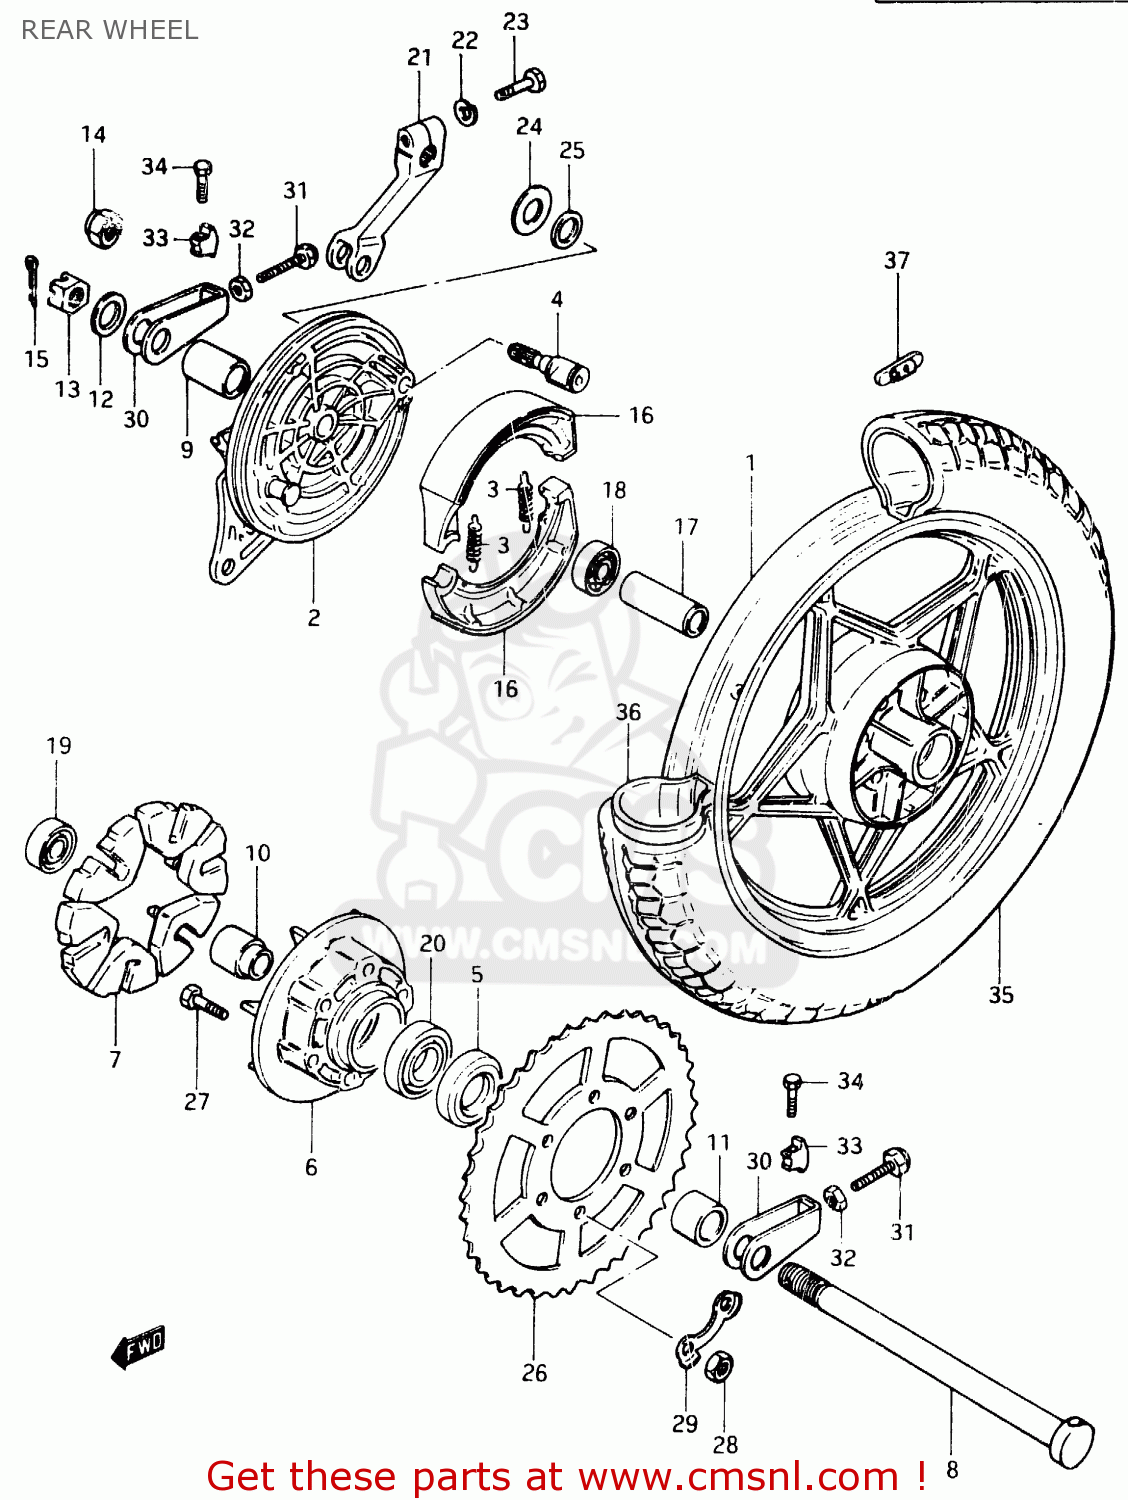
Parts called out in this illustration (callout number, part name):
1	CASTING WHEEL,REAR 1.85-
2	PANEL,REAR HUB
3	SPRING,BRAKE SHOE
4	CAM,FRONT BRAKE
5	SEAL,OIL(30.5X52X8)
6	DRUM,REAR SPROCKET MOUNT
7	ABSORBER,RR HUB SHOCK
8	AXLE, REAR
9	SPACER (17.5X28X51.8)
10	SPACER,REAR HUB BEARING
11	SPACER(17X30.5X16.3)
12	WASHER (17X30X3.2)
13	NUT
14	NUT
15	PIN,COTTER
16	SHOE,BRAKE
17	SPACER (17.6X24X57)
18	BEARING
19	BEARING
20	BEARING
21	LEVER,RR BRAKE CAM
22	LOCK WASHER
23	BOLT
24	WASHER (15X24X1.6)
25	O-RING,BOSS
26	SPROCKET,REAR
27	BOLT
28	NUT
29	WASHER
30	ADJUSTER,CHAIN
31	BOLT 8X50
32	NUT
33	SUPPORTER,CHAIN ADJUST
34	BOLT
35	TIRE (3.75S-18)
36	TUBE,INNER
37	BALANCER,WHEEL
